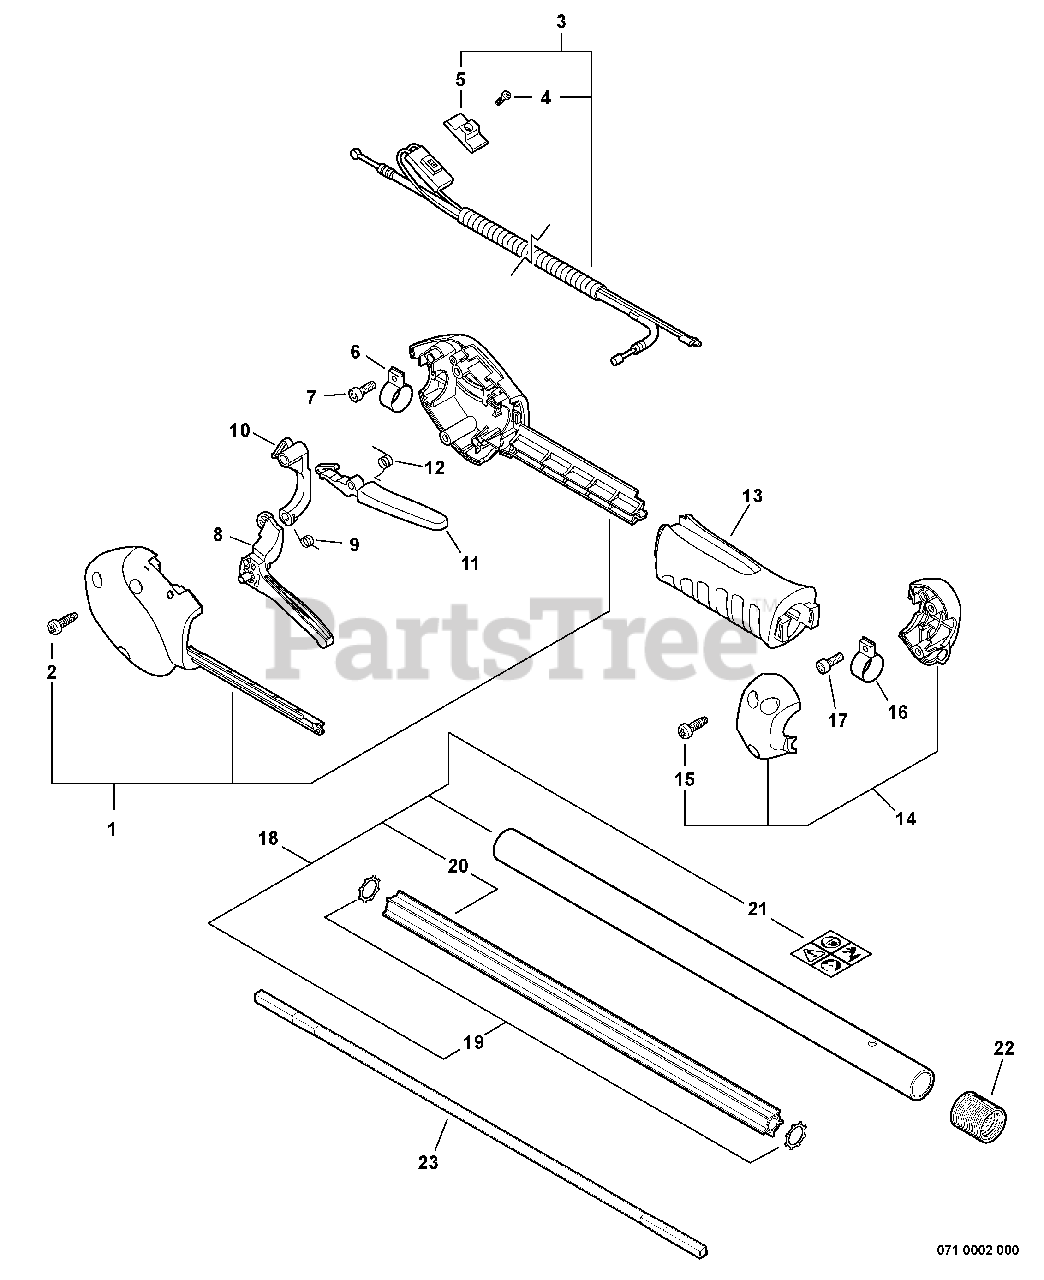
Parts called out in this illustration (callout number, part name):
1	CONTROL HANDLE KIT
2	SCREW - 5X20
3	CONTROL CABLE ASSY
4	SCREW - 3X10
5	KNOB, SWITCH - ORANGE
7	SCREW - 5X20
8	TRIGGER, THROTTLE
9	SPRING, TRIGGER
10	LOCKOUT, THROTTLE
11	LEVER, TRIGGER LOCKOUT
12	SPRING, LOCKOUT LEVER
13	GRIP, HANDLE
14	HANDLE RETAINER KIT
15	SCREW - 5X20
17	SCREW - 5X20
18	PIPE ASSY
21	LABEL - CAUTION
22	TUBE, PROTECTIVE - CORRUGATED
23	DRIVESHAFT - FLEXIBLE
